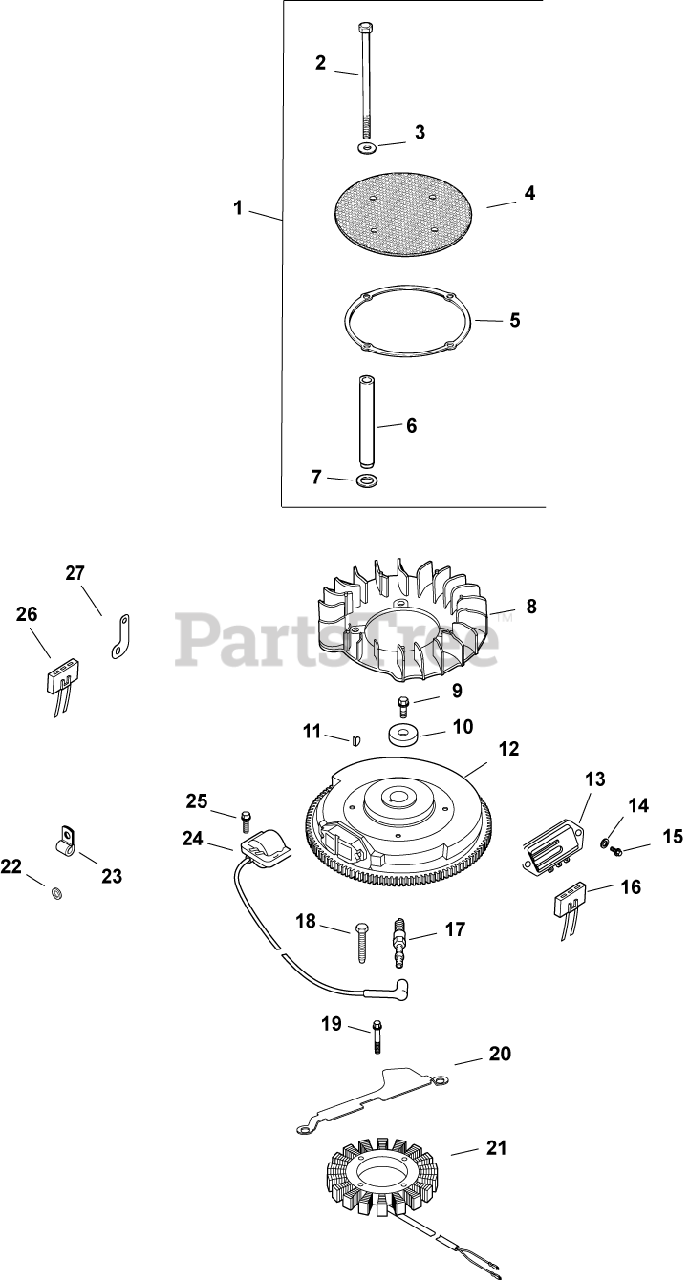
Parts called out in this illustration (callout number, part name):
1	KIT, CHOPPER SCREEN
2	SCREW, CAP M6X1.0X99.5
3	WASHER, FLAT 1/4" (O.D. 5/8")
4	SCREEN, GRASS-USE 24 162 41-S
5	RING, SUPPORT USE 25 141 08-S
7	WASHER, SPRING 10 MM
8	FAN (KM)-USE 24 157 15-S
9	SCREW, FLG M10X1.5X45 - (#25086361S)
10	WASHER, FLAT 13/32"
11	KEY, 3/16" X 5/8"
12	FLYWHEEL, PAINTED-USE 24 025 55-S
13	REG/RECT-15 AMP (KM)-USE 41 403 10-S
14	WASHER, FLAT 3/16"
15	SCREW, PHL HD #11-16X7/8"
16	CONNECTOR, BODY (KM)-USE 25 155 41-S
17	PLUG, SPARK (STD)
18	SCREW, M5X0.8X25 - (#25086402S)
19	SCREW, SKT SET #10-24X1/4"
20	BRACKET, STATOR WIRE
21	KIT, 15 / 20 AMP STATOR
22	WASHER, FLAT 1/4" (O.D. 1/2")
24	MODULE, IGNITION-USE 24 584 45-S
25	SCREW, FLG THD FRM M5X.8X20-(#25086399S)
26	CONNECTOR
27	BRACKET, GROUND STRAP USE 24 518 12-S
